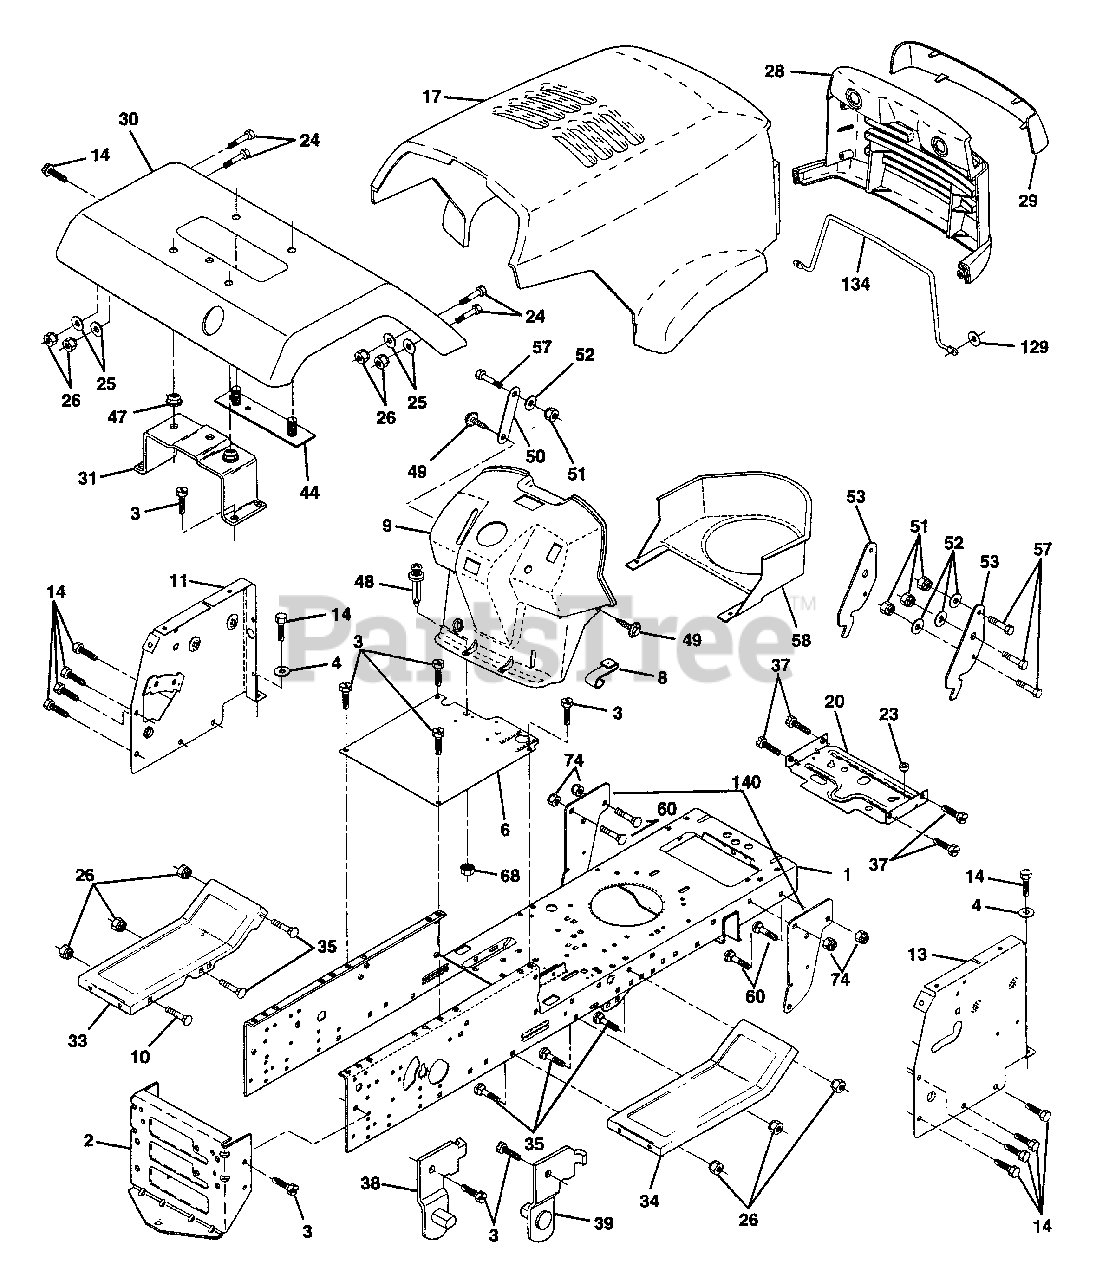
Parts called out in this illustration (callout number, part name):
1	Chassis Weldment 11 ga
2	Drawbar, Stretch
3	Screw Thdrol 3/8-16x3/4 Ty-tt
4	Washer 13/32 x 3/4 x 16 Ga.
6	Saddle LT Fender Shift
8	Clip Insulator .406 Mtg Hole
9	Dash P/L N/Amm. W/HM w/PTO Grey
10	Bolt Carriage 3/8-16 x 1
11	Panel Pnt Dash Lh
13	Panel Dash Rh
14	Screw Thdrol 3/8-16x1/2 Ty-tt
17	Hood LT/PL Husqvarna
20	Plate Mtg. Battery Fuel Tank. 95
24	Bolt Fin Hex 3/8-16unc X 1 Gr. 5
25	Washer 13/32 X 13/16 X 12 Ga
26	Nut Lock Hex W/Ins 3/8-16 Unc
28	Grille LT/PL Husqvarna
29	Lens LT/PL Husqvarna
30	Fender Pnt
31	Bracket Pnt Fender
33	Footrest Pnt Lh
34	Footrest Pnt Rh
35	Bolt Rdhd Sht Sqnk 3/8-16 X3/4
37	Screw Thdrol 5/16-18 X 1/2
38	Bracket, Asm. Pivot, L.H., Mower Rear
39	Bracket, Asm. Pivot, R.H., Mower Rear
44	Strap Asm., Fender 94
47	Nut, Push Nylon
48	Rivet Push Plate D Plastick Blk
49	Screw, Hexwsh. Thdrol 1 /4-20 x 3/4
51	Nut Lock Hex W/Ins 1/4-20
52	Washer 9/32 x 7/8 x 16 Ga.
53	Bracket Pnt. Pick off LT/PL Husq.
57	Bolt Hex 1/4-20 x 3/4
58	Air Duct P/L
60	Bolt Rdhd Snk 3/8-16 UNC x 3/4
68	Nut Keps Hex 1/4-20
74	Nut Crownlock 3/8-16 UNC
129	Washer 9/32 x 5/8 x 16 Ga.
134	Rod Support Hood LT/PL Husq.
140	Bracket Chassis Front
